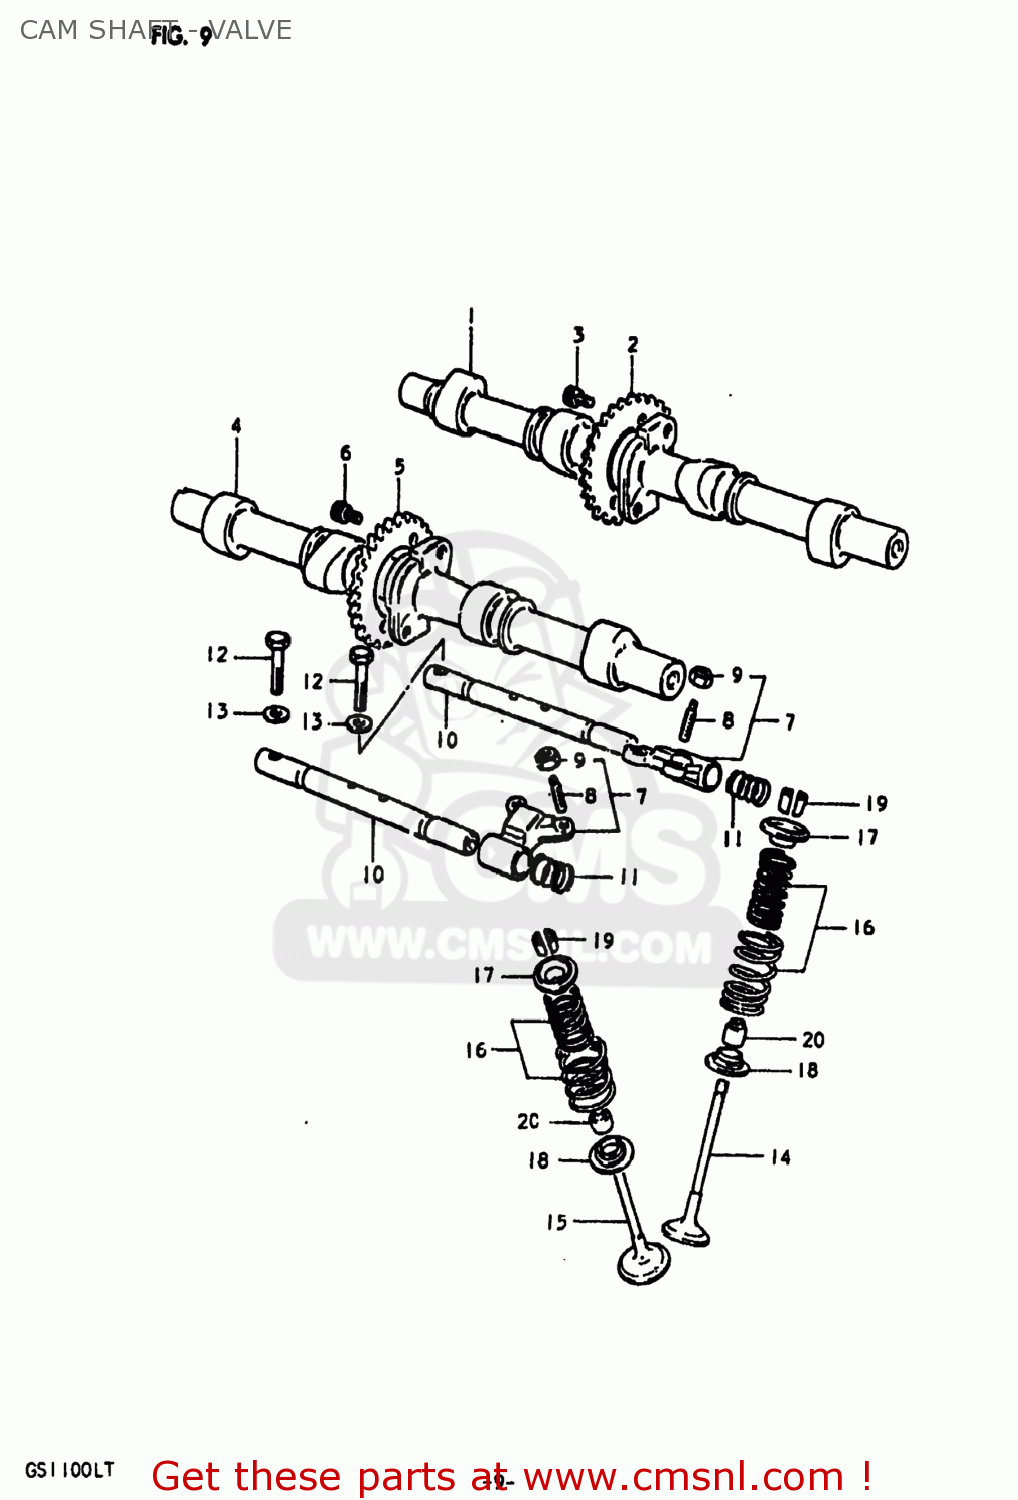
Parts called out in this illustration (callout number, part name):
1	CAMSHAFT
2	SPROCKET,CAMSHAFT
3	BOLT 6X11
4	CAMSHAFT,EXHAUST
5	SPROCKET,EXHAUST CAMSHAFT
6	BOLT 6X11
7	ARM,VALVE ROCKER
8	SCREW,TAPPET ADJUSTING
9	NUT,ADJUSTING
10	SHAFT,VALVE ROCKER
11	SPRING
12	BOLT
13	WASHER
14	VALVE,INTAKE
15	VALVE,EXHAUST
16	SHIM,TAPPET
17	RETAINER,VALVE SPRING
18	SEAT,VALVE SPRING
19	COTTER VALVE
20	OIL SEAL
